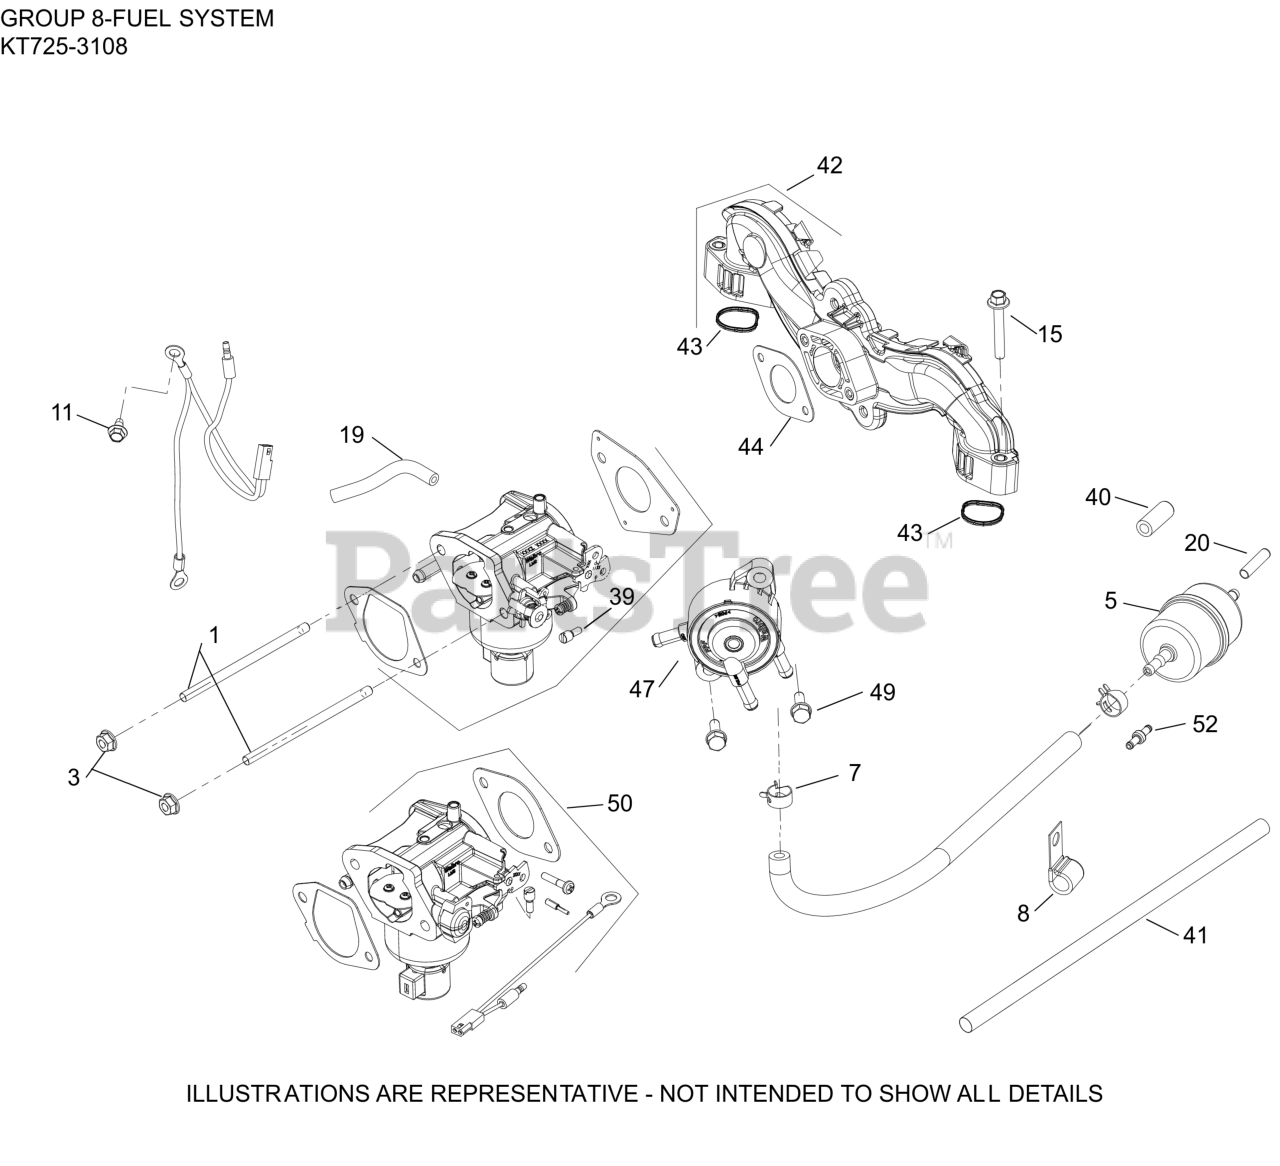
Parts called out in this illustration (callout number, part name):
3	NUT, FLG M6X1.0
5	FILTER, FUEL
7	SPRING CLAMP, HOSE
8	CLIP, CABLE (KM)
11	SCREW, THREAD FORMING
15	SCREW, FLG M6X1.0X40
19	HOSE, EVAPORATIVE 20"- (#24326143S)
20	CAP, MASKING
39	SCREW, THROTTLE STOP
40	MASKING CAP
41	SLEEVE, ANTI-ABRASION
42	INTAKE MANIFOLD W/GASKETS
43	O-RING, INTAKE PORT
44	GASKET, CARBURETOR (PIM, CV)
47	PUMP, FUEL (PULSE)
49	SCREW, HEX HEAD
50	KIT, CARBURETOR COMPLETE
52	FITTING, FUEL SYSTEM
NI	KIT,REPAIR OVERHAUL(WALBRO)
NI	KIT,BOWL O-RING(WALBRO)
NI	KIT, HIGH ALT (4000-8000 FT)WALBRO)
NI	KIT,SOLENOID REPAIR(WALBRO)
NI	KIT,REPAIR FLOAT(WALBRO)
